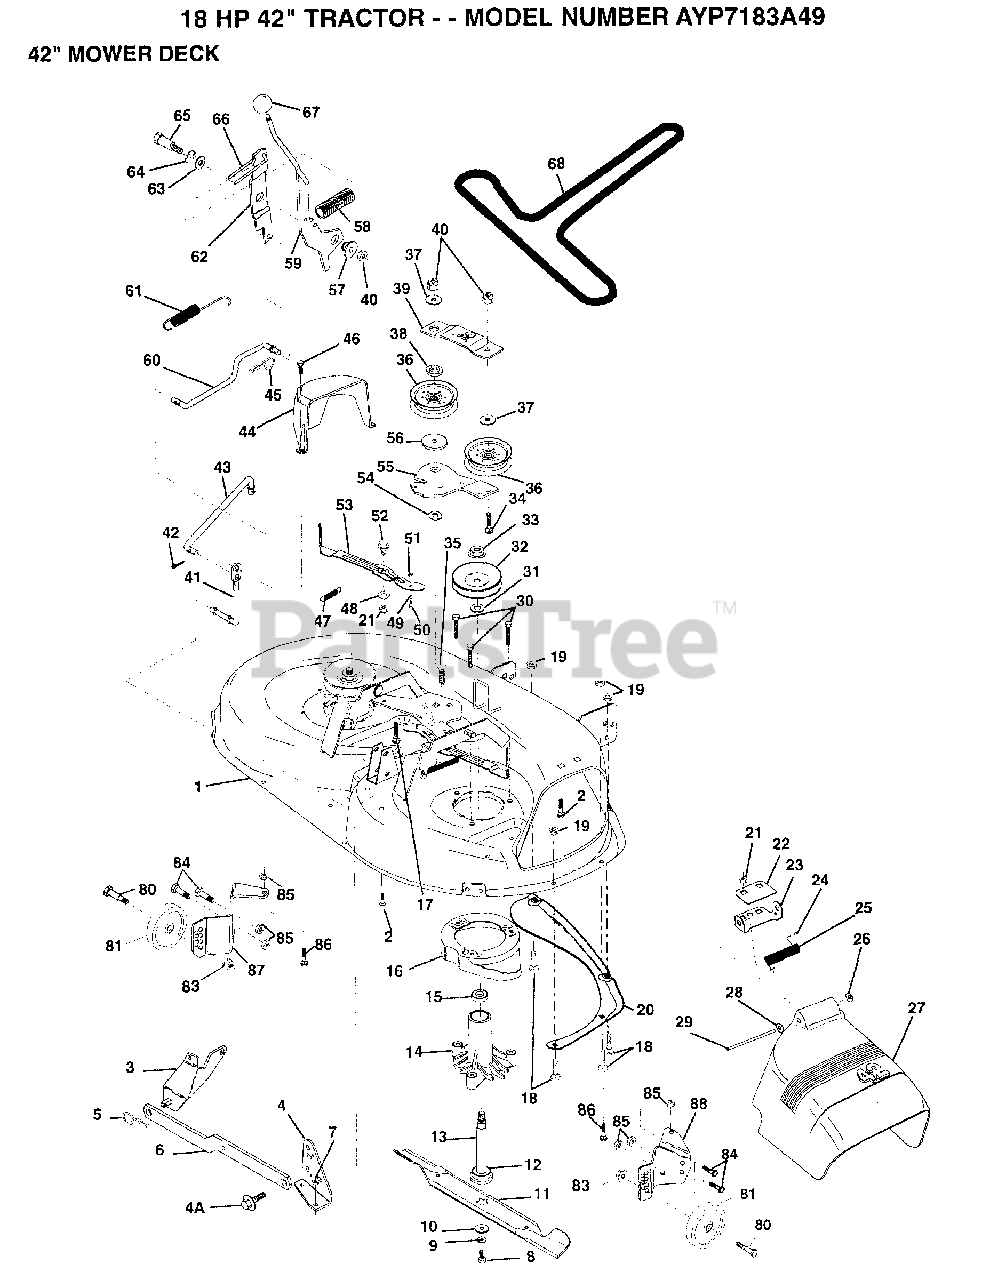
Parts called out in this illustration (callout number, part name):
2	BOLT
3	BRKT ASM SWAY BAR
4	BRKT DECK SW BAR
4A	BOLT SHD 5/16-18
7	NUT
8	BLADE BOLT
10	WASHER.HARD.BLADE
11	"BLADE.42"" MULCHER"
12	BEARING.BALL
14	HSG ASM MANDREL
15	BEARING
17	BOLT CARRIAGE
18	BOLT
19	NUT
22	STIFFENER BRKT
23	DEFLECTOR BRKT
24	CAP-SLEEVE LT
25	SPRING TORSION
26	NUT PUSH M
27	DEFLECTOR.SHIELD
28	WASHER
29	HINGE ROD
31	WASHER
34	BOLT
35	XMAS TREE FASTNER
36	FLAT IDLER PULLEY
37	WASHER GT
38	RETAINER SPACER
39	IDLER ARM STIFF
41	PIVOT ROD
43	CLUTCH ROD SECOND
44	GUARD MAND LH BLK
45	RETAINER M
46	SCREW.1/4-20X5/8
47	SPRING EXTENSION
48	HARD SMALL WASHER
50	SHOULDER BOLT
51	LOCKNUT
52	BOLT.SHLD.5/16-18
53	BRAKE PAD ARM ASM
54	HARDENED WASHER
55	IDLER ARM
56	SPACER RETAINER
57	BUSHING
59	CLUTCH ARM PRI AS
60	"ROD, CLUTCH PRIM"
61	RETURN SPRING
62	CLUTCH ARM SECOND
63	WASHER
64	RING
65	SHOULDER BOLT
66	SPRING KEEPER
67	KNOB T(3/8 HOLE)
68	BELT-V.92.4.MWR
80	BOLT M
81	WHEEL.GAGE.BLK.PL
83	NUT
84	BOLT
